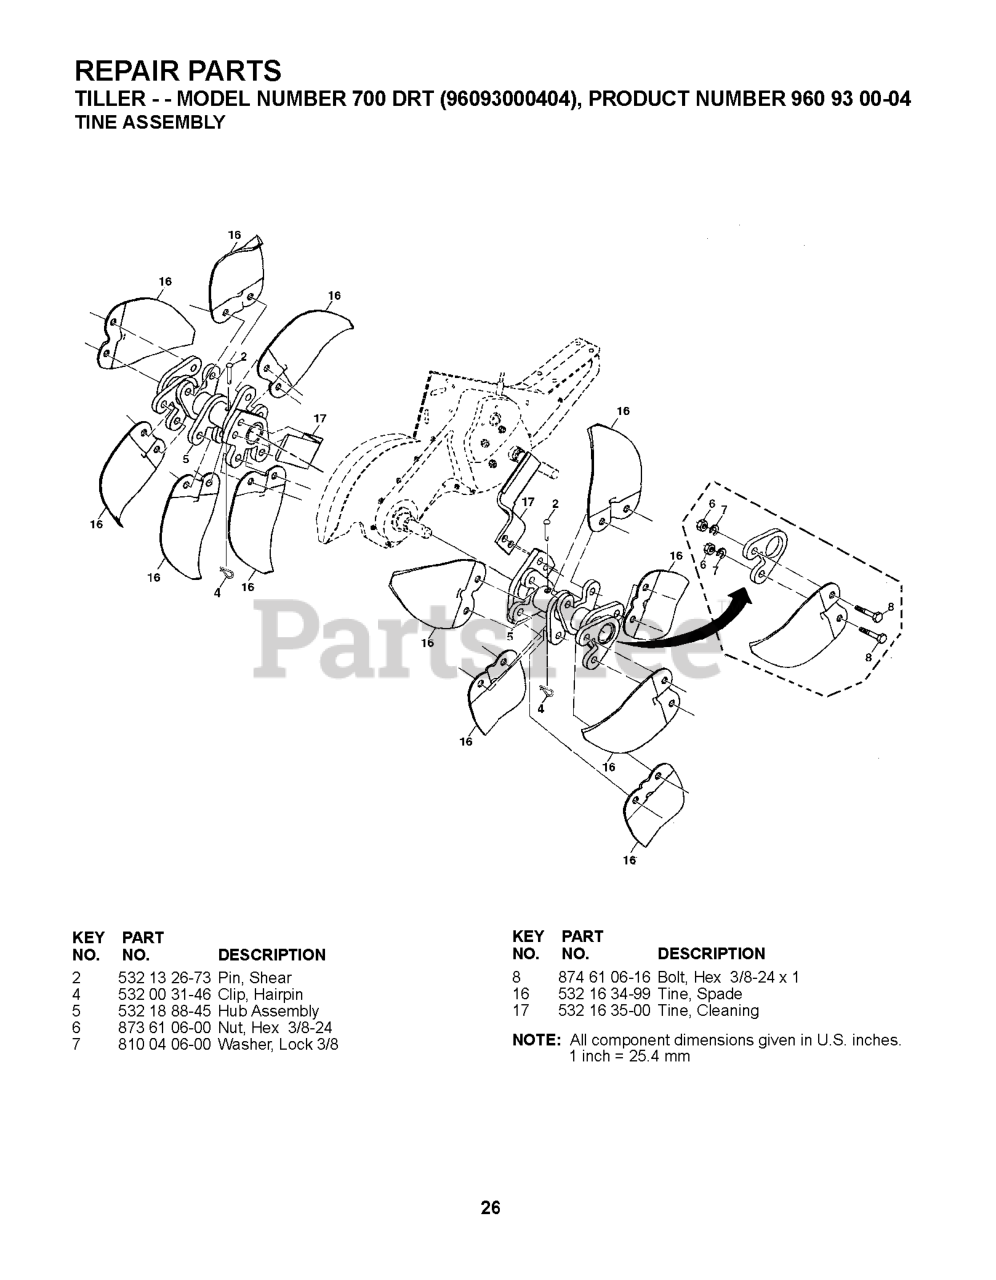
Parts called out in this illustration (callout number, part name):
2	PIN RETAINING SCREW
4	SPRING RETAINER
5	HUB.ASM.DRT17.2004 (CMPL KIT)
6	NUT
7	WASHER, LOCK 3/8
8	BOLT.HEX.001X20.37-24X1.ZINC
16	TINE.SPADE
17	TINE.CLEANING BLACK
